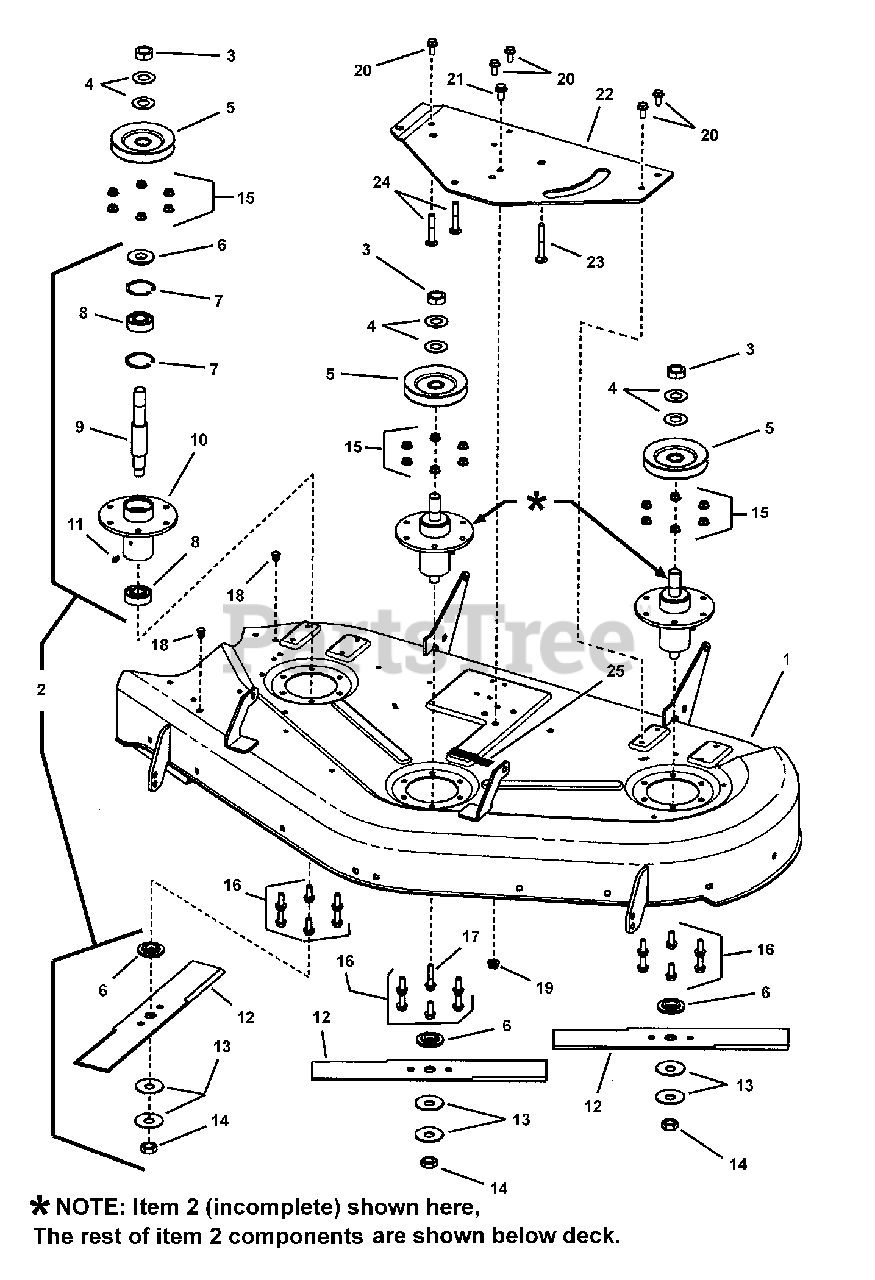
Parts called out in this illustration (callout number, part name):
1	HOUSING, 44"
2	GROUP, Spindle, 44" SMI, ERZT
3	NUT, Hex, Jam, 3/4F GR8
4	WASHER, .77X1.5X.06
5	PULLEY, 4.75 O.D.
6	WASHER, Spindle, Powdered Metal
7	RETAINING RING, Extension, 1.75
8	BEARING, Spindle
9	SHAFT, Spindle
10	WELD, Spindle
11	LUBE FITTING
12	BLADE, 16-1/8", No Air-Lift, ERZT
13	WASHER, Bellville, .656X1.875X.086
14	NUT, Hex, Jam, 5/8F ZP
15	NUT, Hex Flange Lock, 5/16C GR5 YZ
16	CAPSCREW, Hex Head, Whiz Lock, Flange, 5/16C X7/8 YZ
17	CAPSCREW, Hex Head, Whiz Lock, Flange, 5/16C X1-1/2 GR5 YZ
18	PLUG, Hole, Polyethelene
19	NUT, Hex Flange Lock, 3/8C YZ
20	CAPSCREW, Hex Head Flange Taptite, 5/16C X3/4 YZ
21	CAPSCREW, Hex Head, Whiz Lock, Flange, 3/8C X3/4 GR5 YZ
22	BRACKET, Idler Pulley, 44/50"
23	CARRIAGE BOLT, 3/8C X2-3/4 GR5 YZ
24	CARRAIGE BOLT, 3/8-16 X 2-1/4, GR5
25	PAD, Rubber Adhesive
